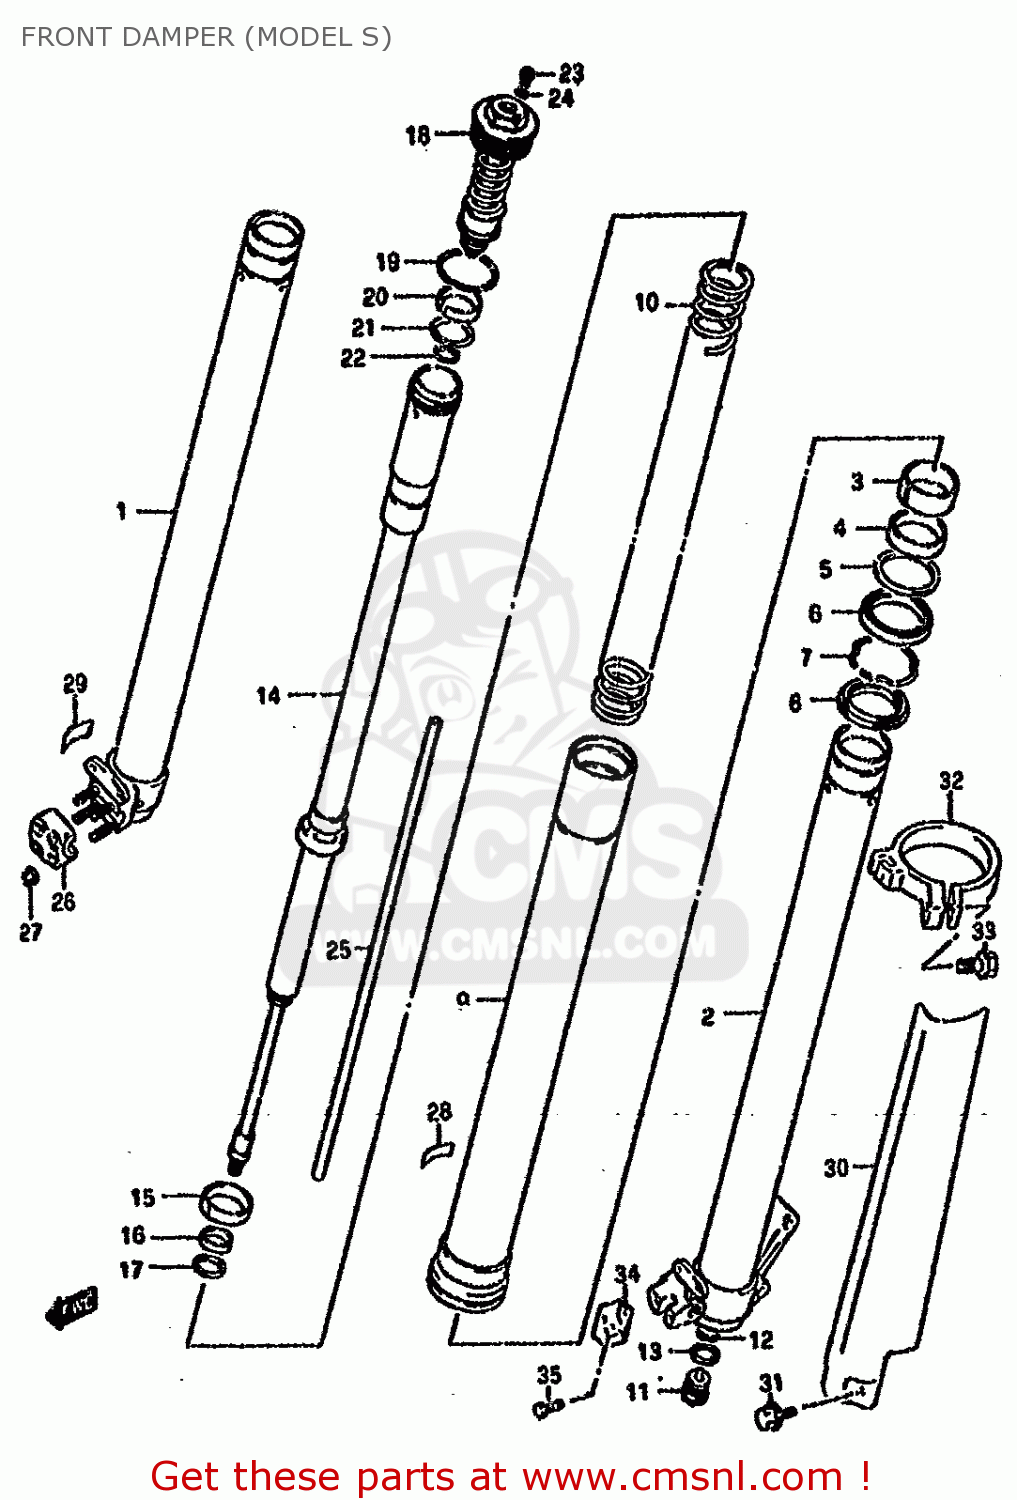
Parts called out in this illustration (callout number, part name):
1	TUBE,INNER,RIGHT
2	TUBE,INNER,LEFT
3	BUSH,SLIDE
4	BUSH,GUIDE
5	SPACER,SEAL
6	SEAL,OIL
7	RING,OIL SEAL STOPPER
8	SEAL,DUST
9	TUBE,OUTER
10	SPRING,MAIN
11	BOLT,CTR
12	GASKET (NAS)
13	O RING,CTR BOLT
14	DAMPER,CARTRIDGE
15	BUSH,DAMPER SLIDE
16	VALVE,OIL LOCK
17	RING,VALVE STOPPER
18	BOLT,FORK
19	O RING
20	BUSH,FORK BOLT SLIDE
21	O-RING,FORK BOLT,CENTER
22	O-RING,FORK BOLT,LOWER
23	BOLT,PLUG
24	O RING,PLUG
25	ROD,PUSH
26	HOLDER,AXLE,R
27	NUT
28	LABEL
29	LABEL
30	PROTECTOR,FORK,R
31	BOLT,PROTECTOR(6X10)
32	GUIDE,FORK PROTECTOR
33	BOLT,PROTECTOR GUIDE,6
34	GUIDE,HOSE,L
35	BOLT
36	SPRING,MAIN
